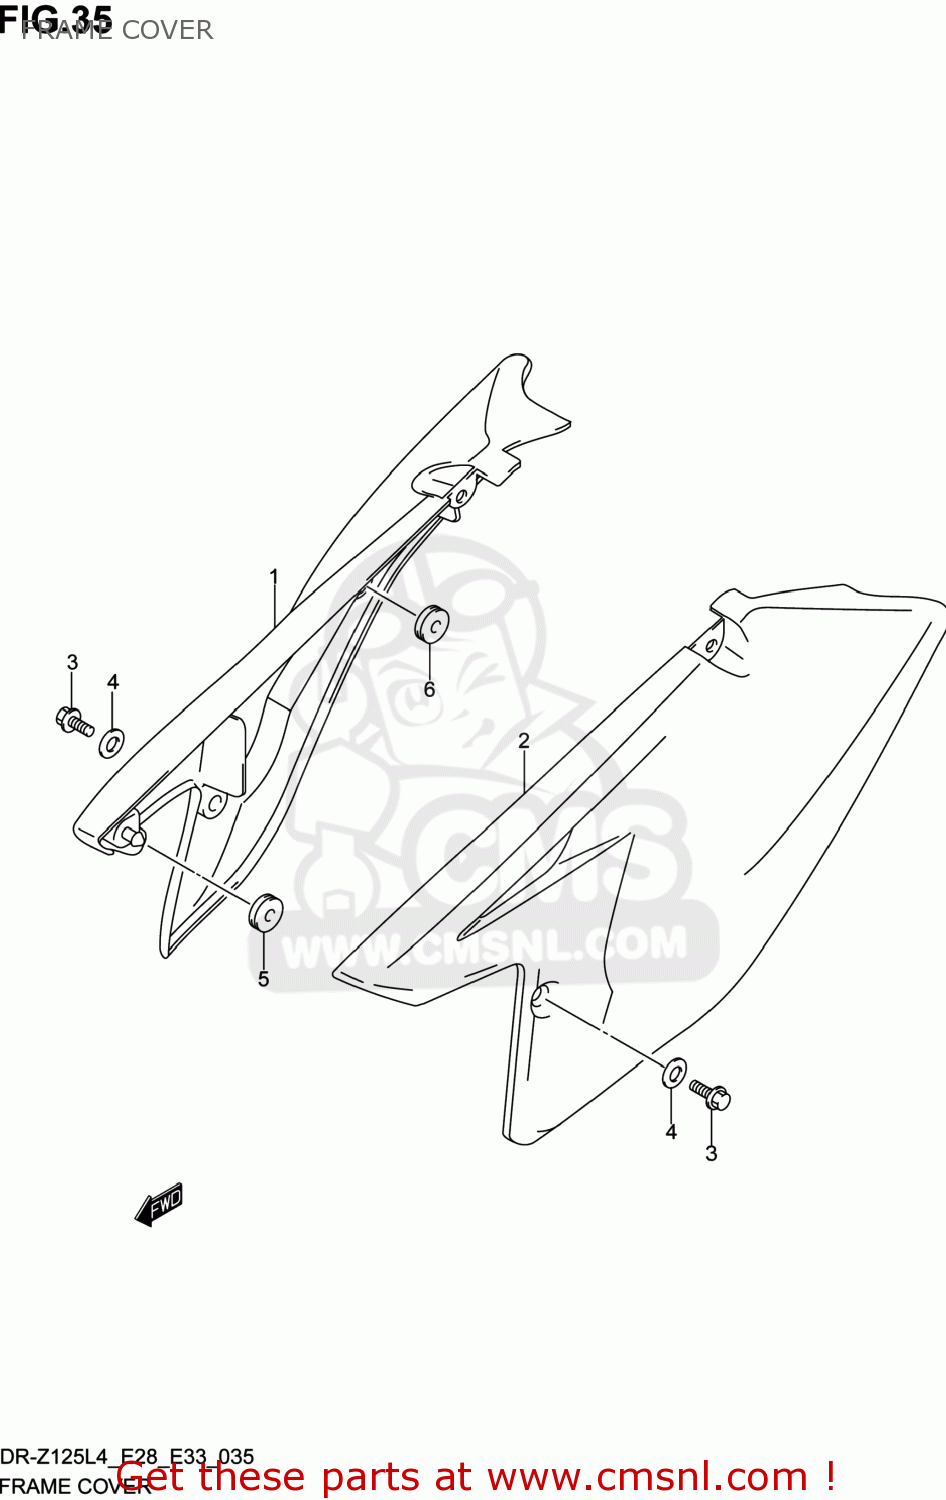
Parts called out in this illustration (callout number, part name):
1	COVER,FRAME,R(WHITE)
2	COVER,FRAME,L(WHITE)
3	BOLT
4	WASHER
5	CUSHION
6	CUSHION
